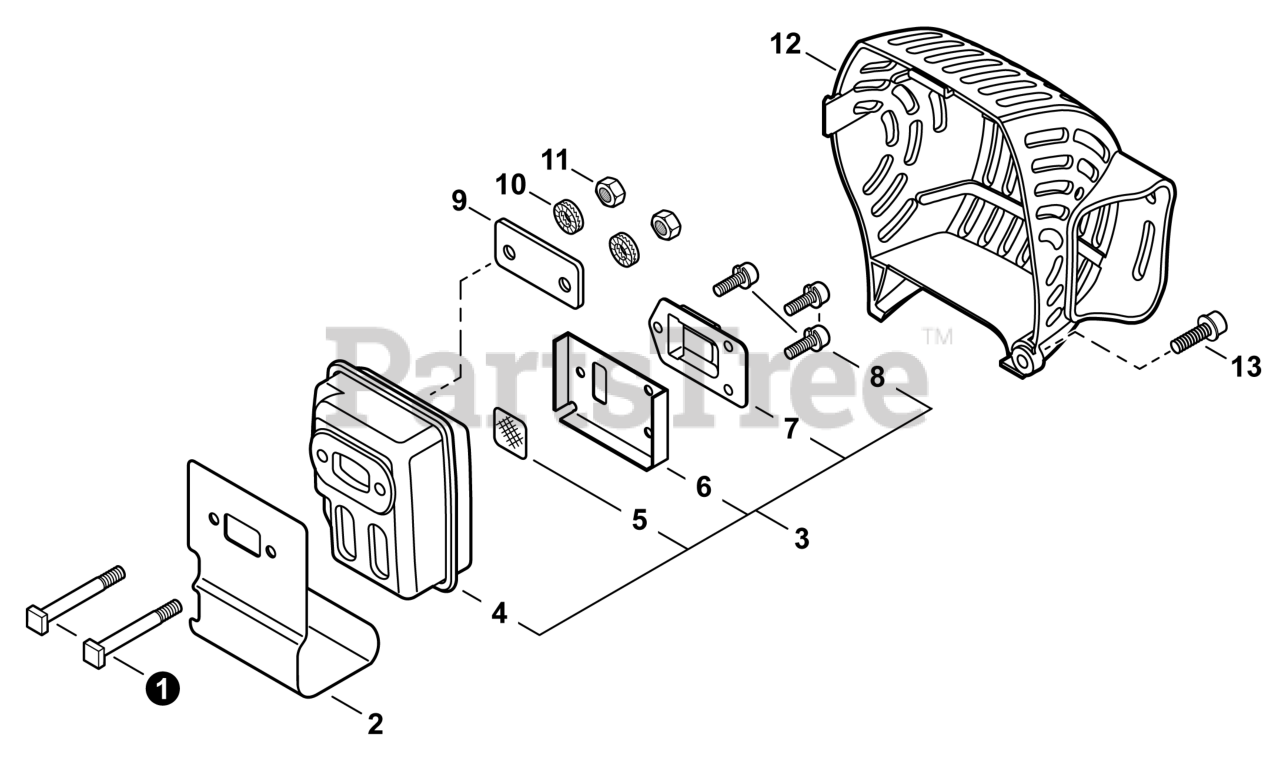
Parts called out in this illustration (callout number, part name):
1	BOLT 5x60
2	HEAT SHIELD, EXHAUST
3	MUFFLER ASSY
4	MUFFLER
5	SCREEN, SPARK ARRESTER
6	GASKET, EXHAUST
7	GUIDE, EXHAUST
8	SCREW 4x10
9	PLATE, EYE
12	COVER, MUFFLER
13	BOLT 5x14
